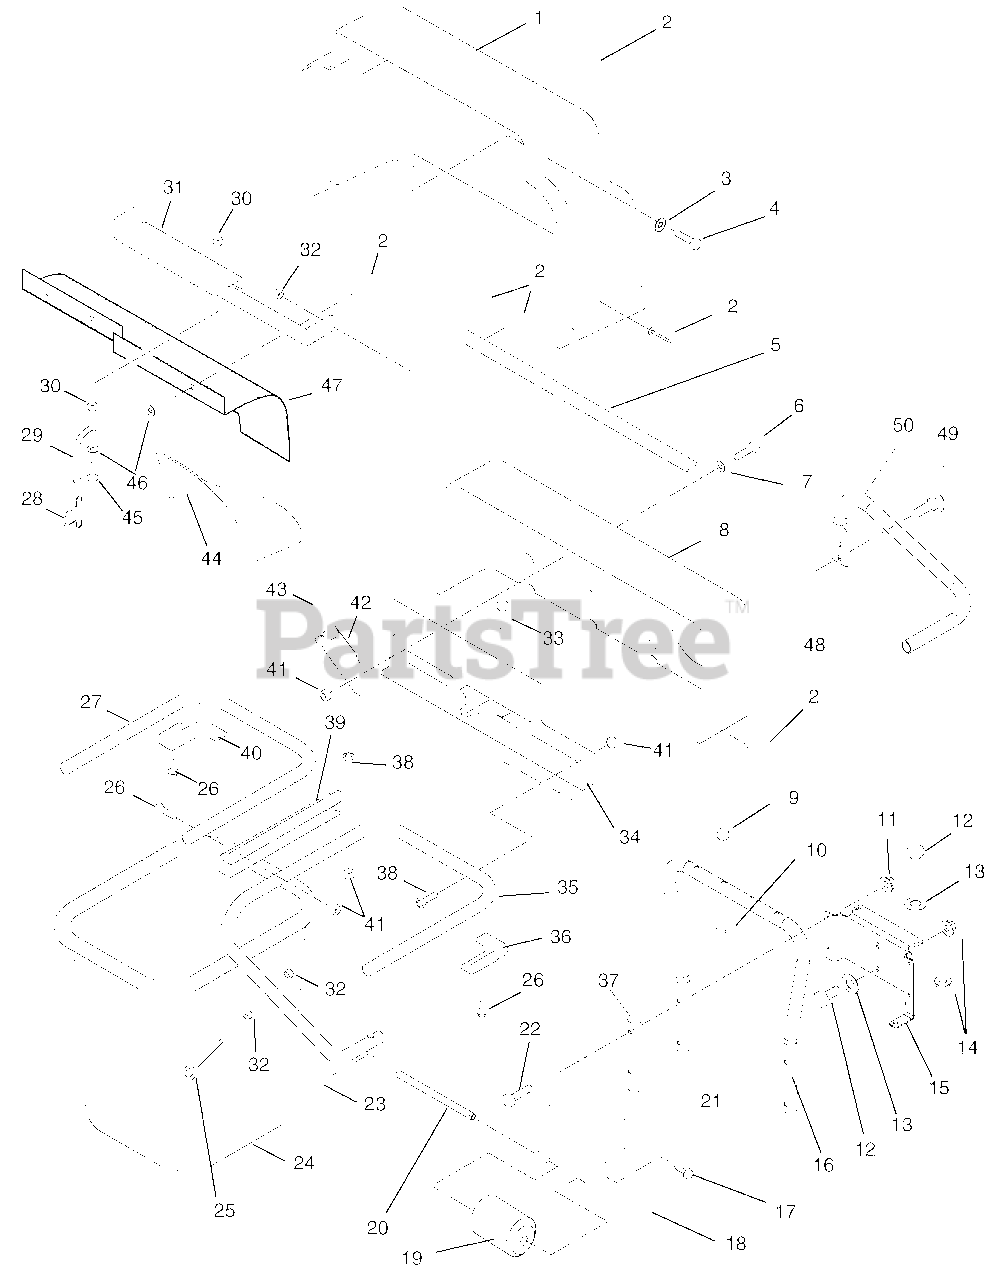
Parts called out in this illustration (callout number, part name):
1	Hinged Cover w/Decals
2	Rivet-Pop .187 x .402
3	Washer-Flat-Steel .281 x .62 x .065
4	Bolt-Hex .25-20 x .50 Grade 5
6	Bolt-Hex .31-18 x .75 Grade 2
7	Washer-Flat-Steel .328 x .875 x .062
8	Stationary Cover
9	Nut-Hex .31-18 Grade 2
10	Nut-Wing .312-18
11	Nut-Locking-Top-Flange .31-18
12	Bolt-Hex .38-16 x 1.00 Grade 5
13	Washer-Flat-Steel .38 x .875 x .083
14	Nut-Locking-Top-Flange .38-16
15	Bracket, Bagger Mount
17	Screw
18	Cotter Pin
20	Roll Pin
22	Bolt-Hex .31-18 x 1.50 Grade 5
23	Pin-Hair Internal .08 x .38 x 1.42
24	Grass Bagger Basket
26	Screw-Tapping .31-18 x .50
27	Center Tube
28	Hook
29	Battery Strap
30	Nut-Locking Top 10-24
31	Cover Bracket
32	Nut-Locking-Center .250-20
33	Bolt-Hex .31-18 x 1.75 Full Thread
34	Mounting Bracket
35	Right Tube
36	Right Hand Corner Bracket
37	Service Bar Brace (827016)
38	Screw-Machine .31-18 x 1.50
39	Tube Bracket
40	Left Hand Corner Bracket
41	Nut-Locking .312-18
42	Brace
43	Rivet-Pop .187 x .527
45	Screw-Machine 10-24 x .88
46	Washer-Flat-Steel .219 x .50 x .049
48	Nut-Flange, .375-16
49	Bolt-Round Head Square Neck .38-16 x .75 Grade 5
50	Support, 28-Inch Bagger Tube
